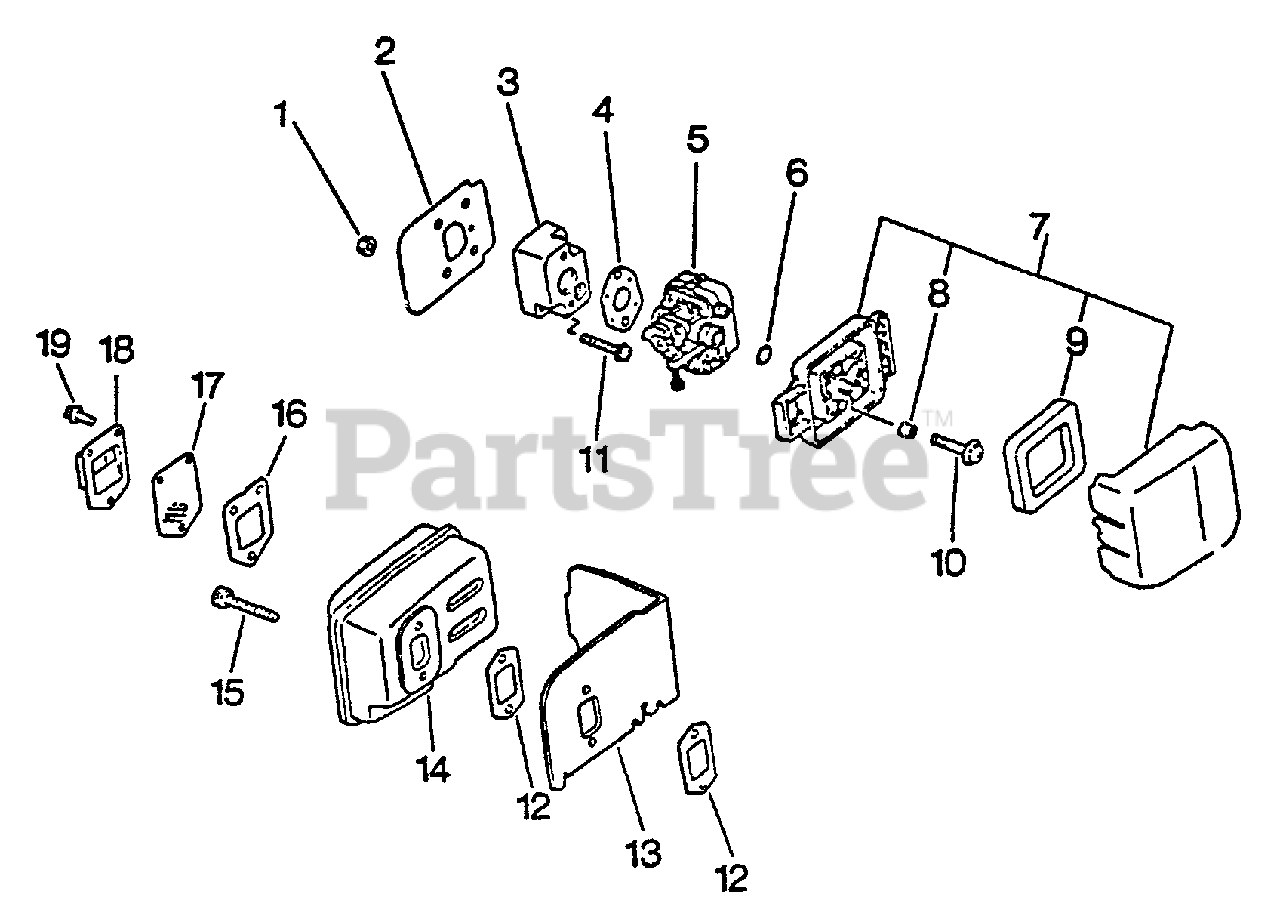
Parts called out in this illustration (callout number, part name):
1	NUT M5
2	HEAT SHIELD, INTAKE
3	INSULATOR, INTAKE
4	GASKET, INTAKE
5	CARBURETOR
6	O-RING 15
7	AIR FILTER ASSY
8	SLEEVE
9	FILTER, AIR
10	SCREW 5×64
11	SCREW 5×22
12	GASKET, EXHAUST
13	COVER, EXHAUST
14	MUFFLER
15	BOLT 5×55
16	GASKET, EXHAUST
17	SCREEN, SPARK ARRESTER
18	GUIDE, EXHAUST
19	SCREW 4×10
